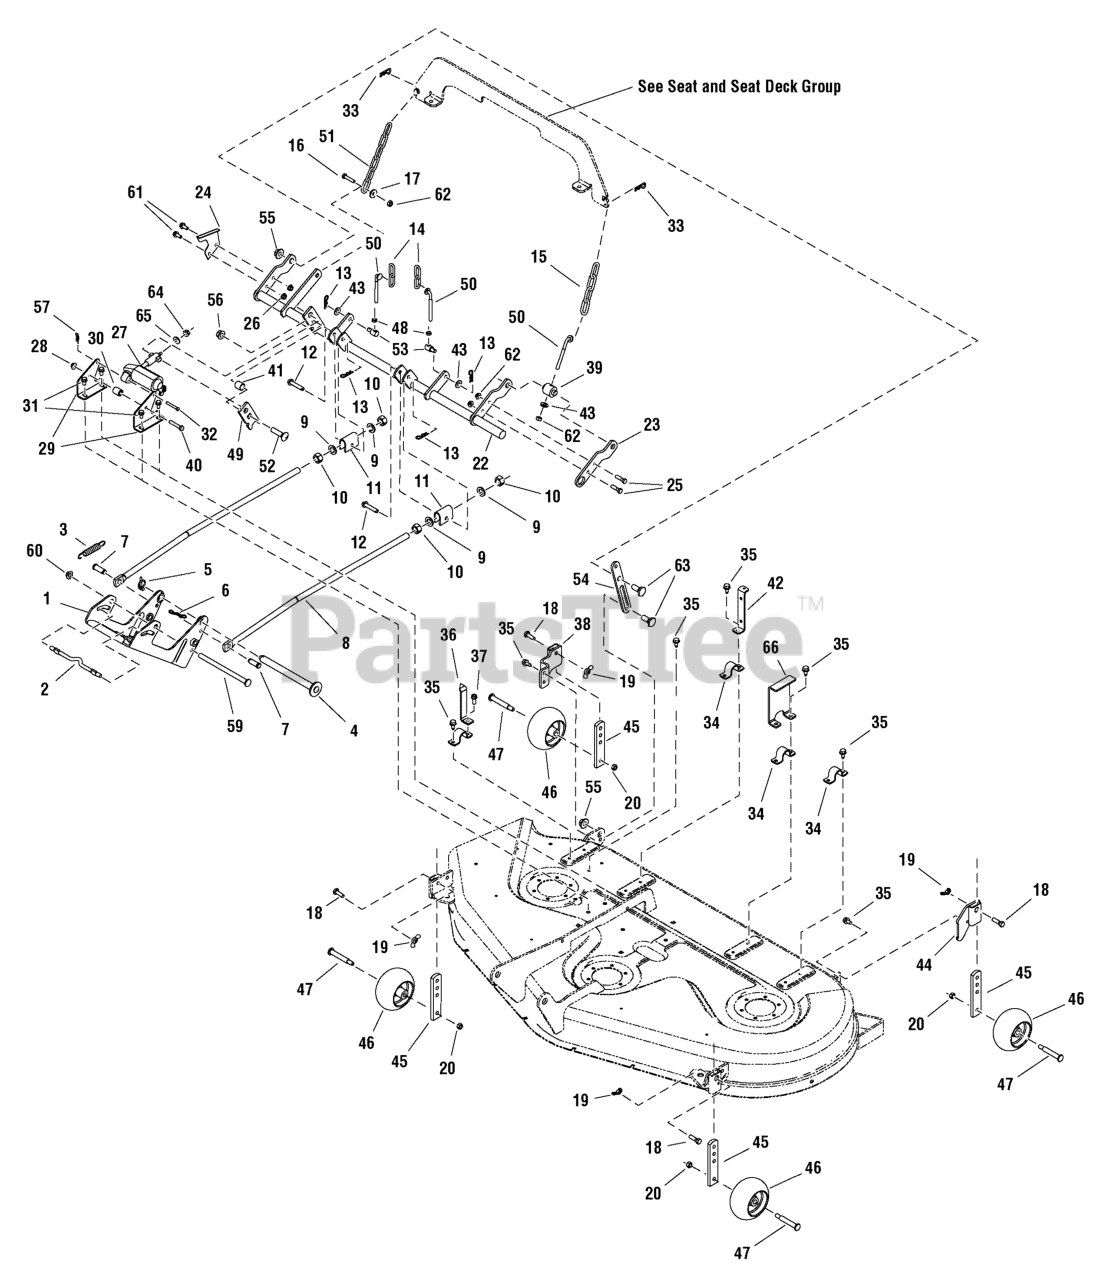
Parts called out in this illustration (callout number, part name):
1	HITCH & ROD ASSEMBLY, 54"
2	ROD, 3/8 x 8
3	SPRING, Extension
4	ASSEMBLY, Hitch Pin
5	PIN, Klik, 3/16 x 1-5/8
6	PIN, Cotter Locking
7	PIN, Yoke, 1/2
8	ROD, 5/8 x 29-5/8 Long
9	WASHER, 5/8
10	NUT, Hex, Jam, 1/2-13
11	TRUNNION, Bracket
12	PIN, Round Head Drilled 3/8 x 2
13	CLIP, Hair Pin
14	CHAIN, 2-Link
15	CHAIN, 4-Link
16	CAPSCREW, Hex Head, 5/16-18 x 1-1/2 G5
17	WASHER, Plain, 11/32 x 1 x 1/8
18	CAPSCREW, Hex, 3/8-16 x 1-1/4
19	NUT, WING, 3/8-16
20	NUT, Hex Flange, 2-Way Lock, 3/8-16
22	ROCKER SHAFT, Frame Hung, 54"
24	BRACKET, Cutting Height
25	CAPSCREW, Hex Head, 5/16-18 x 1
26	NUT, Hex Whiz Lock, 5/16-18
27	MOTOR, Linear Actuator Deck Lift
28	NUT, Hex Flange Whiz Lock Large, 5/16-18
29	BRACKET, Mounting
30	SPACER, 0.39 x 3/4 x 0.965
31	CAPSCREW, Taptite, 5/16-18 x 5/8
32	PIN, Shear, 1-3/4
33	CLIP, Hair Pin
35	CAPSCREW, Hex Head, Taptite, 5/16-18 x 3/4
36	INDICATOR, Height of Cut
37	CAPSCREW, Hex Head Taptite, 5/16-18 x 1-1/4
38	GAGE, Wheel Assembly, R.H.
39	TRUNNION
40	SCREW, Hex Head Cap, 5/16-18 x 1 3/4
41	SPACER, .66 ID
42	UPSTOP, Rear
43	WASHER, Plain, 3/8
44	GAUGE WHEEL ASSEMBLY
45	POST, Anti-Scalp
46	WHEEL, Gauge
47	BOLT, Shoulder, 3/8-16
48	NUT, Hex, Jam, 5/16-18
49	ARM, Rocker
50	ADJUSTER, Chain
51	CHAIN, 6 Link, 8 13/32 Long
52	BOLT, Carriage, Short Neck, 1/2-13 x 2
53	TRUNNION, 5/8 OD x 1-11/32 Long
54	STOP, Height Adjusting
55	NUT, Hex Flange, Two-Way Lock, 1/2-13
56	NUT, Hex, Toplock Flange,1/2-13
57	CLIP, Hair Pin Spring
59	ROD, Mower Hitch
60	PUSH NUT, Stud Cap, 1/2
61	CAPSCREW, Hex Flange Hd, Whizlock, 5/16-18 x 3/4
62	NUT, Hex, Flange ESNA, 5/16-18, Black
63	BOLT, Shoulder, 2-9/16 Long
64	NUT, Hex, 1/4-20, L.H. Thread
65	WASHER, Plain, 1/4
